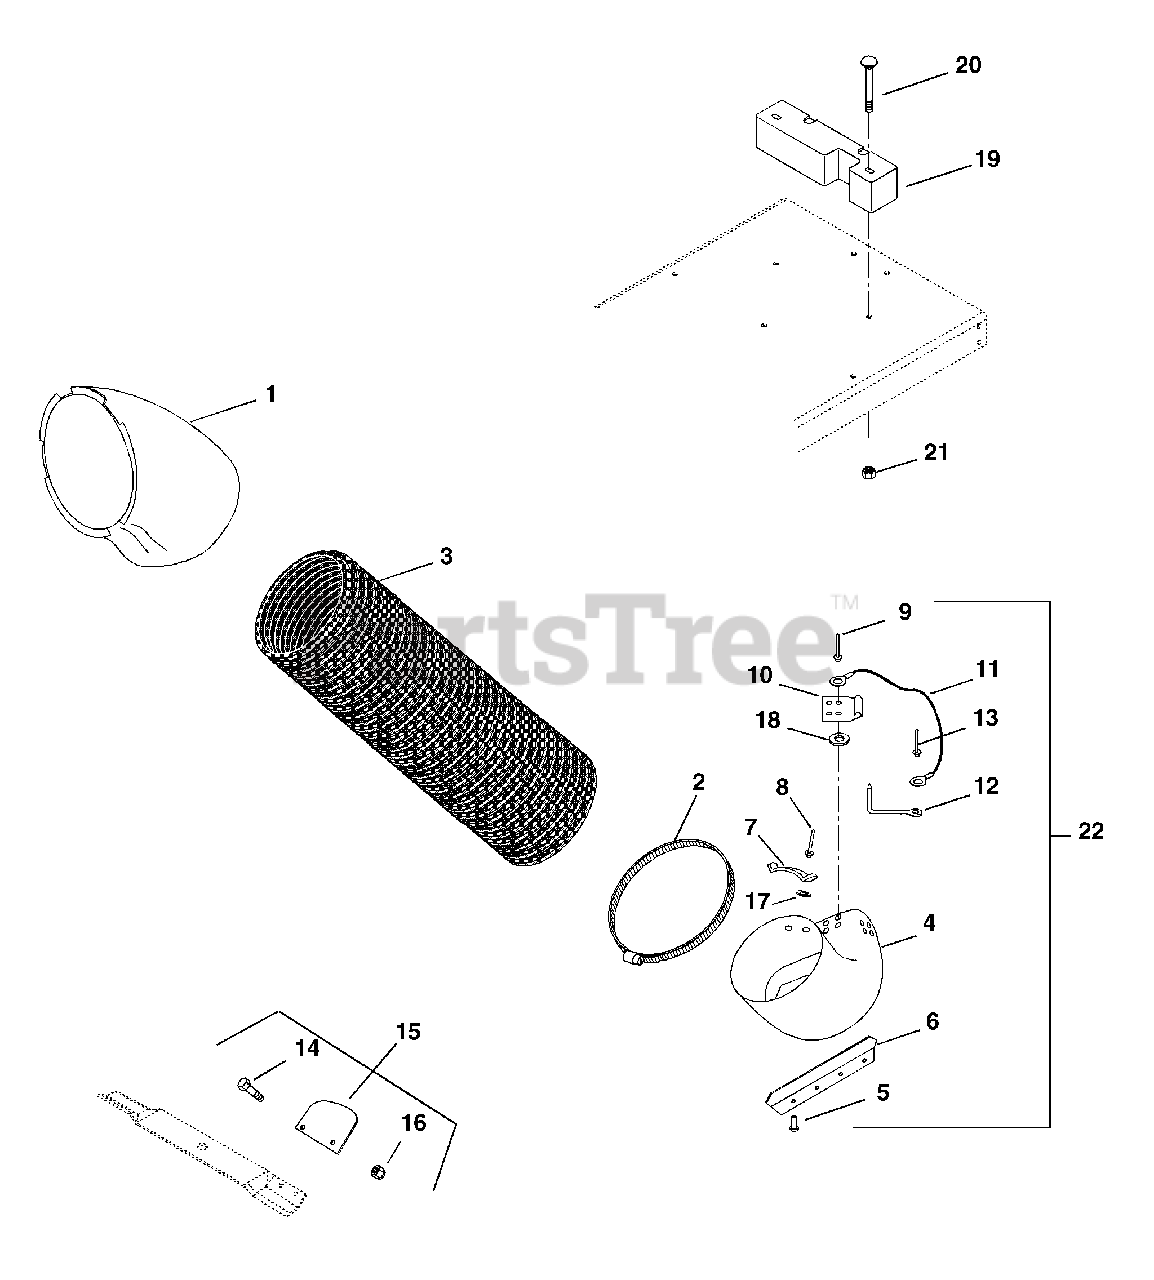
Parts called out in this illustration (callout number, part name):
1	BAGGER BOOT - UPPER
2	CLAMP-HOSE WRM 2.13/8.62X.56
3	HOSE 7X38
4	PAN BOOT ASSEMBLY
5	RVT-TBLR .187X.375 OH ST PL
6	EXTENSION-CHUTE
7	TUBE RETAINER CLIP
8	RVT-POP.187X.527 DOME ST
9	RVT-POP .187X.402 DOME ST
10	BOOT BRACKET
11	LANYARD
12	PULL PIN
13	RVT-TBLR .187X.375 ST-AL PL
14	BLT-HEX .31-24X.75 GR8 YWZC
15	SERVICE VANE PACKAGE
16	NUT-CTRLK .31-24 YWZC
17	@WSHR-FL-STL.219X.50X.049 YWZC
18	@WSHR-FL-STL .188X.438X.049 YZ
19	COUNTER WEIGHT
20	@BLT-RDHDSQNK .44-14X4.50 G2YZ
21	@NUT-LK-CTR .44-14 YWZC
22	MOWER BOOT ASSY- 40"
